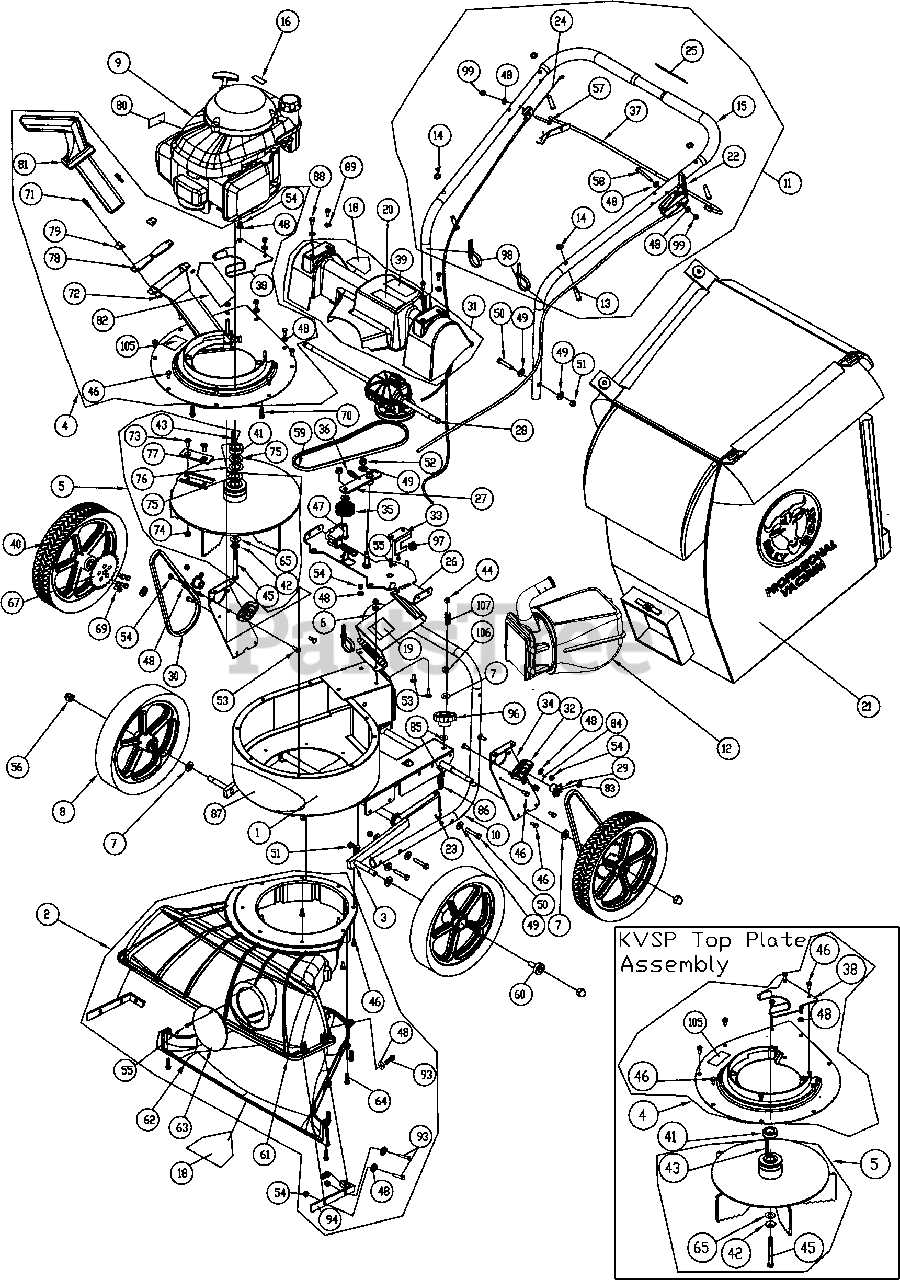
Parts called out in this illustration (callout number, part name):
1	MAIN FRAME HOUSING KV
2	NOZZLE ASSEMBLY TKV
3	AXLE WA KV MICRO
4	PLATE TOP WA KVSP
5	IMPELLER SERRATED 14.25 WA KVSP
6	DOOR EXHAUST ASSY RAW
7	WASHER 1/2" SAE Z/P
8	WHEEL ASSY 12" X 2.5" TREAD
9	ENGINE 6 BRIGGSAND STRATTON
10	LOWER HANDLE KV
11	HANDLE UPPER KVSP
12	QUICK DISCONNECT
13	PIN CLEVIS 3/8" x 2.125" LONG
15	GRIP HANDLE 1"X 9.5" LG
16	LABEL HOT ENGINE EN/SP
18	LABEL WARNING DANGER
19	LABEL DANGER FLYING DEBRIS
20	LABEL SAFETY PROTECT READ MANUAL
21	BAG DEBRIS NO ZIPPER KV
22	CABLE THROTTLE ASSY 42" W/CHOKE
23	J BOLT 3/8-16 X 6"
24	CABLE CLUTCH DRIVE ASSY 40" KVSP
25	LABEL CLUTCH VQ
26	BRACKET TRANS MOUNT WA KV
27	ARM IDLER DRIVE WA KV
28	TRANS SINGLE SPEED W/DIFF
29	SPROCKET 8 TOOTH #43 OR #65
30	CHAIN #43 X 58 PITCHES
31	GUARD DRIVE KV
32	BEARING 1/2" PRESSED STEEL HOUSING
33	BRACKET TRANS FIX KV
34	PLATE CHAIN REINFORCE KV
35	PULLEY IDLER 2" OD X 3/8" ID
36	SPRING TENSION
37	BAIL CLUTCH WA KVSP
38	BRACKET IDLER BELT FINGER KV
39	LABEL DANGER GUARD
40	WHEEL ASSY SP 26T SPROCKET
41	SPACER 1.50OD X .890ID X .5 THK
42	WASHER LOCK 3/8 ST MED
43	SQ KEY 2.125 X .187
44	NUT LOCK 3/8-16 THIN
45	SCREWCAP 3/8-24 x 3 1/2 GR. 8 W/PATCH
46	SCREWCAP 1/4 - 20 x 5/8 HWH
47	BOLT IDLER 3/8-16 X 1 1/2
48	WASHER 1/4" SAE ZP
49	WASHER 5/16 FLATWASHER Z/P
50	SCREWCAP 5/16-18 X 1.75 ZP
51	NUT LOCK 5/16-18
52	NYLON INSERT LOCKNUT, 3/8-16 UNC
53	SCREWCAP 1/4-20 X 3/4"
54	NYLON INSERT LOCKNUT, 1/4-20 UNC
55	SCREWCAP #10-14 X 3/4" HWH ZP
56	1/2-13 CAP NUT NP W/PATCH
57	SCREWCAP 1/4-20 x 1 3/4 HCS ZP
58	SCREWCAP 1/4-20x2"
59	BELT 3V315
60	BEARING BALL FLANGED
61	NOZZLE TOP HALF KV
62	NOZZLE BOTTOM HALF KV
63	PLUG HOUSING KD LB
64	SCREW PLASTIC 1/4-20 X 1
65	WASHER 1.5 OD X .453 ID X .25 THK
67	SPROCKET 65A26 26 TOOTH
69	SCREW SELF TAP 1/4 x 0.75
70	SCREW PLASTITE 1/4-20 X 3/4 HWH ZP
71	SCREWCAP #10-24 X 5/8"
72	NYLON INSERT LOCKNUT 10-32 UNF ZINC
73	SCREW SOCKET HD 5/16-18 X 3/4 GR. 8
74	NUT KEPS 5/16-18
75	WASHER SHIM 0.875 ID X 0.060
76	WASHER SHIM 0.875 ID X 0.020
77	BLADE CHIPPER KD501
78	GUARD FLAPPER
79	PLATE FLAPPER ENTRANCE
80	LABEL SPARK ARRESTOR EN/SP
81	TAMPER CHIPPER
82	LABEL DANGER CHIPPER
83	CLIP 1/2"
84	WOODRUFF KEY 1/8 X 1/2
85	WASHER 1/2" FC
86	SPRING COMPRESSION
87	LABEL DECAL KV/TKV
88	SCREW SM 1/4 X 3/4 DRILL PT
89	WASHER 1/4" SAE BLACK OXIDE
92	CARRIAGE BOLT 1/4"-20 X 3/4"
93	SCREWCAP 1/4-20 X 1" HCS ZP
94	KV NOZZLE BRACKET
96	KNOB 3/8-16 RED
97	SPRING LEVER GZ
99	NUT 1/4-20 ACORN
105	LABEL MADE IN U.S.A.
106	GROMMET FLANGE 1/2" MOLDED
107	SPRING COMPRESSION
